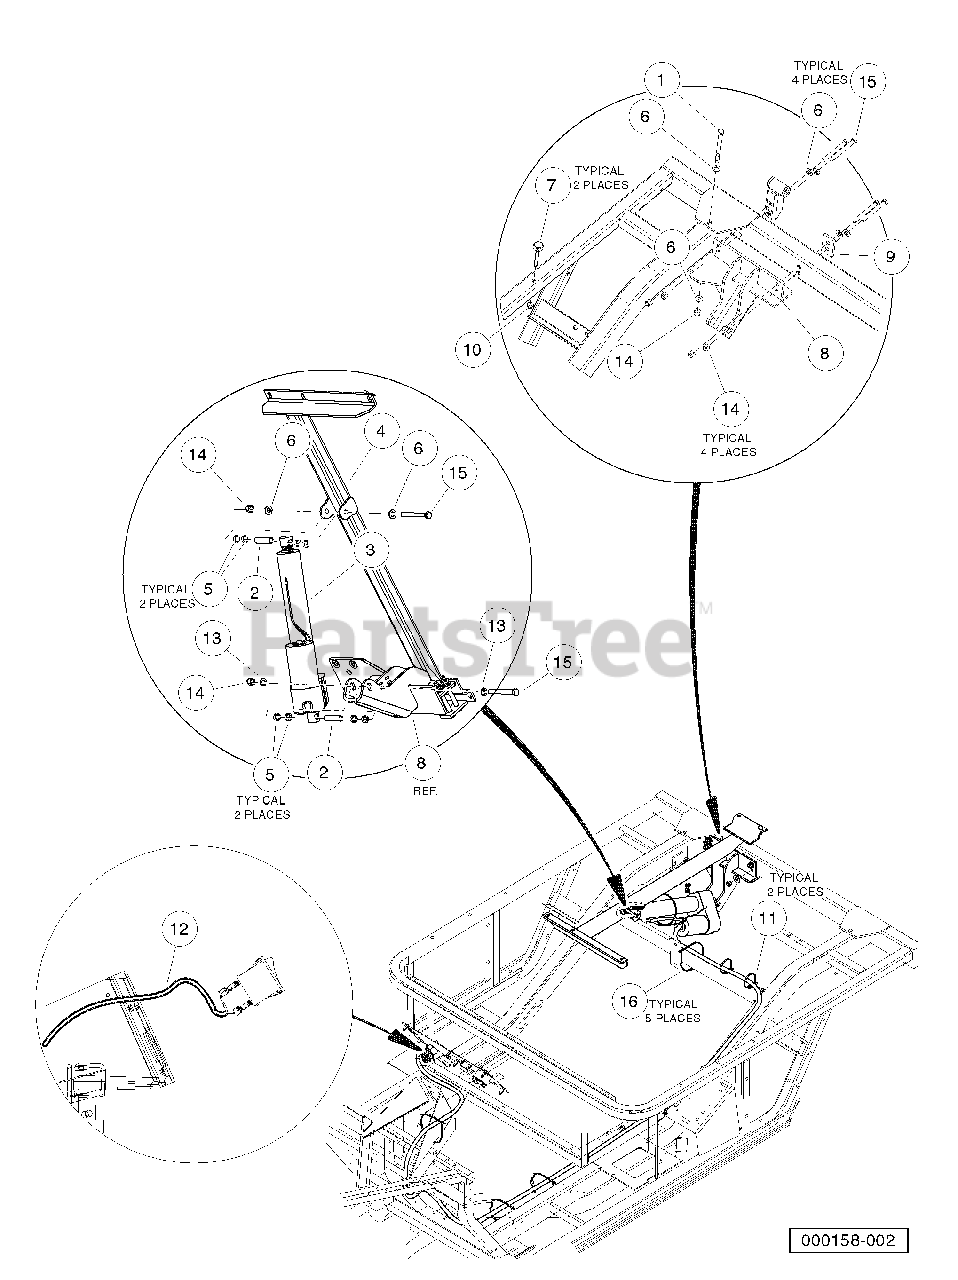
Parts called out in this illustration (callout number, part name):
1	Bolt, 3/8-16 X 4.25 Hex Head
2	Bushing Long
3	Actuator Assembly, Electric
4	Asm, Actuator Adapter
5	Body Spacer
6	Washer, 3/8 Type B Hard Flat
7	Bumper, Bed, Mtg, Front
8	Weldment, Bracket, Actuator
9	Plate, Back
10	Lock Nut, Flg M8 X 1.25 Nylon
11	Tie Wrap, 8.00" With Mount
12	Harness, AWD Bedlift
13	Washer, Lock, Hel Sp 3/8 Reg
14	Locknut, 3/8-16 Hex
15	Screw, 3/8-16 X 3.375 Hex Cap
16	Tie Wrap, 8" Nylon
